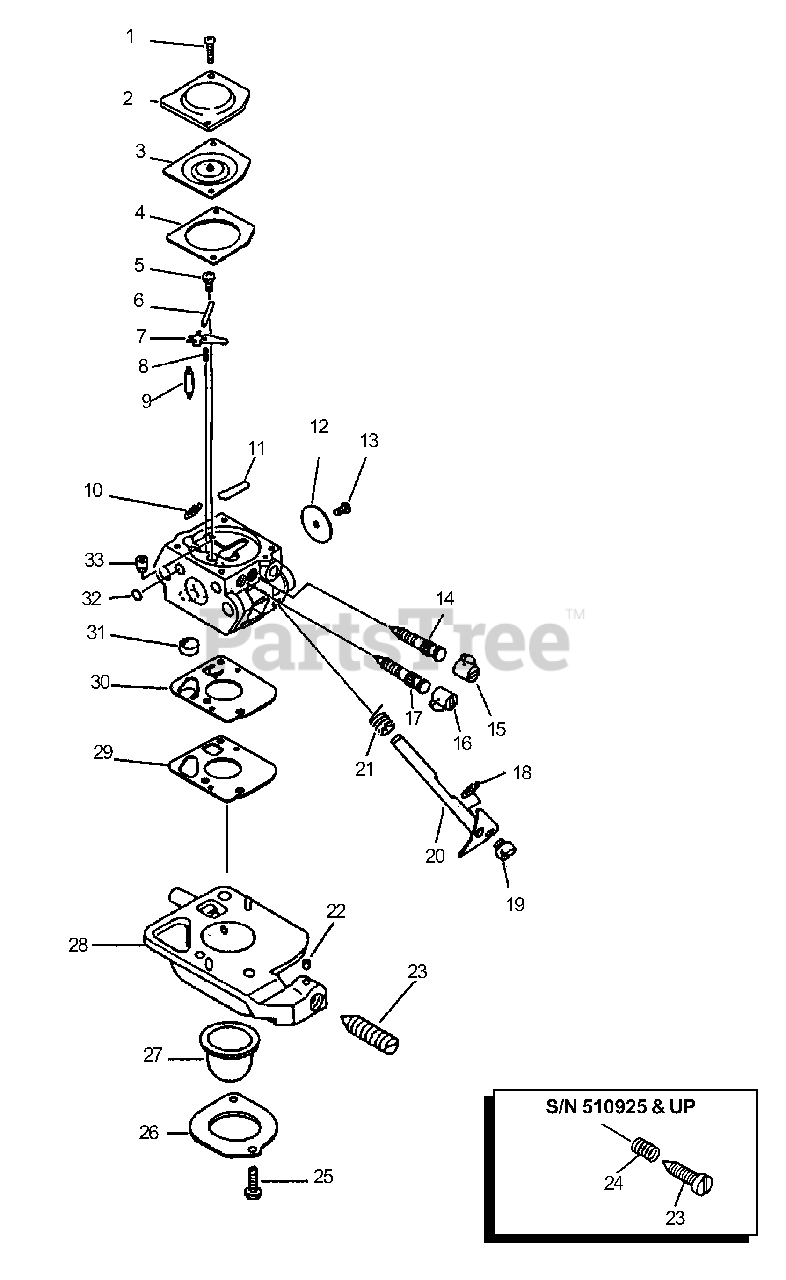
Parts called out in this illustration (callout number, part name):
2	COVER, METERING
3	DIAPHRAGM, METERING
4	GASKET, METERING
5	SCREW, METERING LEVER PIN
6	PIN, METERING LEVER
7	LEVER, METERING
8	SPRING, METERING LEVER
9	VALVE, NEEDLE
10	RING, RETAINING
11	PLUG, WELCH
12	VALVE, THROTTLE
14	NEEDLE - LOW SPEED
15	CAP, LIMITER
16	CAP, LIMITER
17	NEEDLE - HIGH SPEED
18	RING, RETAINING
20	SHAFT, THROTTLE
21	SPRING, RETURN
22	PIECE, FRICTION
23	SCREW, IDLE ADJUST
24	SPRING, IDLE ADJUST
25	SCREW, RETAINER
26	RETAINER, PURGE BULB
27	BULB, PURGE
28	BASE, PURGE
29	GASKET, PURGE
30	DIAPHRAGM, PURGE
31	STRAINER
32	PLUG, WELCH
33	NOZZLE, CHECK VALVE
A	DIAPHRAGM/GASKET KIT
B	REPAIR KIT
